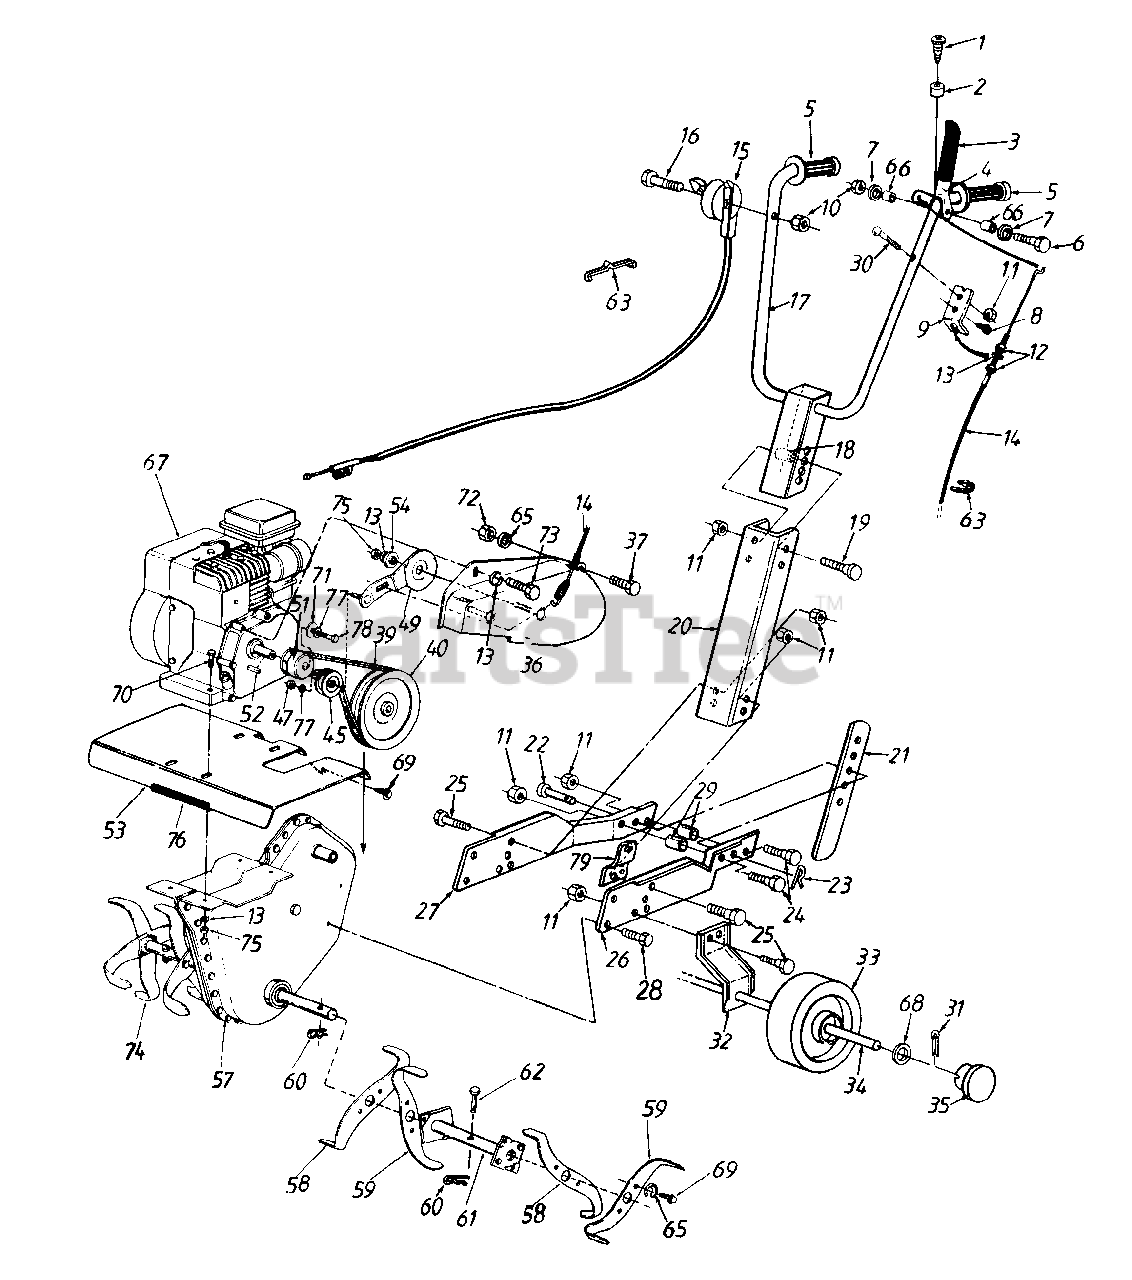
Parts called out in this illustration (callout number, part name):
1	Tap Scr. #10-16 x 1/2" Lg.
2	Rubber Bumper
5	Handle Grip
6	Hex Bolt 1/4-20 x 2" Lg.
7	Fl-Wash. 1/4" I.D.
8	Hex Tap Scr. 1/4-20 x 1/2" Lg.
9	Cable Bracket
10	Lock Nut 1/4-20 Thd.
11	Lock Nut 5/16-18 Thd.
12	Hex Jam Nut 5/16-24 Thd.
13	L-Wash. 5/16" I.D.
14	Clutch Control Cable
15	Throttle Control
16	Hex Bolt 1/4-20 x 1-1/2" Lg.
19	Carr. Bolt 5/16-18 x 2-1/2" Lg.
23	Hairpin Cotter
24	Hex Bolt 5/16-18 x 1" Lg.
25	Hex Bolt 5/16-18 x 5/8" Lg.
29	Spacer
30	Hex Bolt 5/16-18 x 1-1/4" Lg.
31	Cotter Pin
39	V-Belt
40	Pulley - Chain Case
45	Flat Idler Pulley
47	Hex Jam L-Nut 3/8-24 Thd.
49	Idler Arm Ass'y.
51	Engine Pulley
52	Square Key 3/16" x .75" Lg.
53	Tine Shield
54	Washer-Bushing
57	Chain Case Ass'y. Comp.
63	Cable Tie - Plastic
65	L-Wash. 1/4" I.D.
67	Engine
68	Fl-Wash. 3/8" I.D.
69	Tap Scr. 1/4-20 x 1/2" Lg.
70	Hex Bolt 5/16-18 x 1-1/2" Lg.
71	Fl-Wash. 3/8" I.D. x 1" O.D.
72	Hex Nut 1/4-20 Thd.
73	Hex Bolt 5/16-24 x .5" Lg.
77	L-Wash. 3/8" I.D.
78	Hex Bolt 3/8-24 x 1" Lg.
714-01498	Hairpin Cotter
